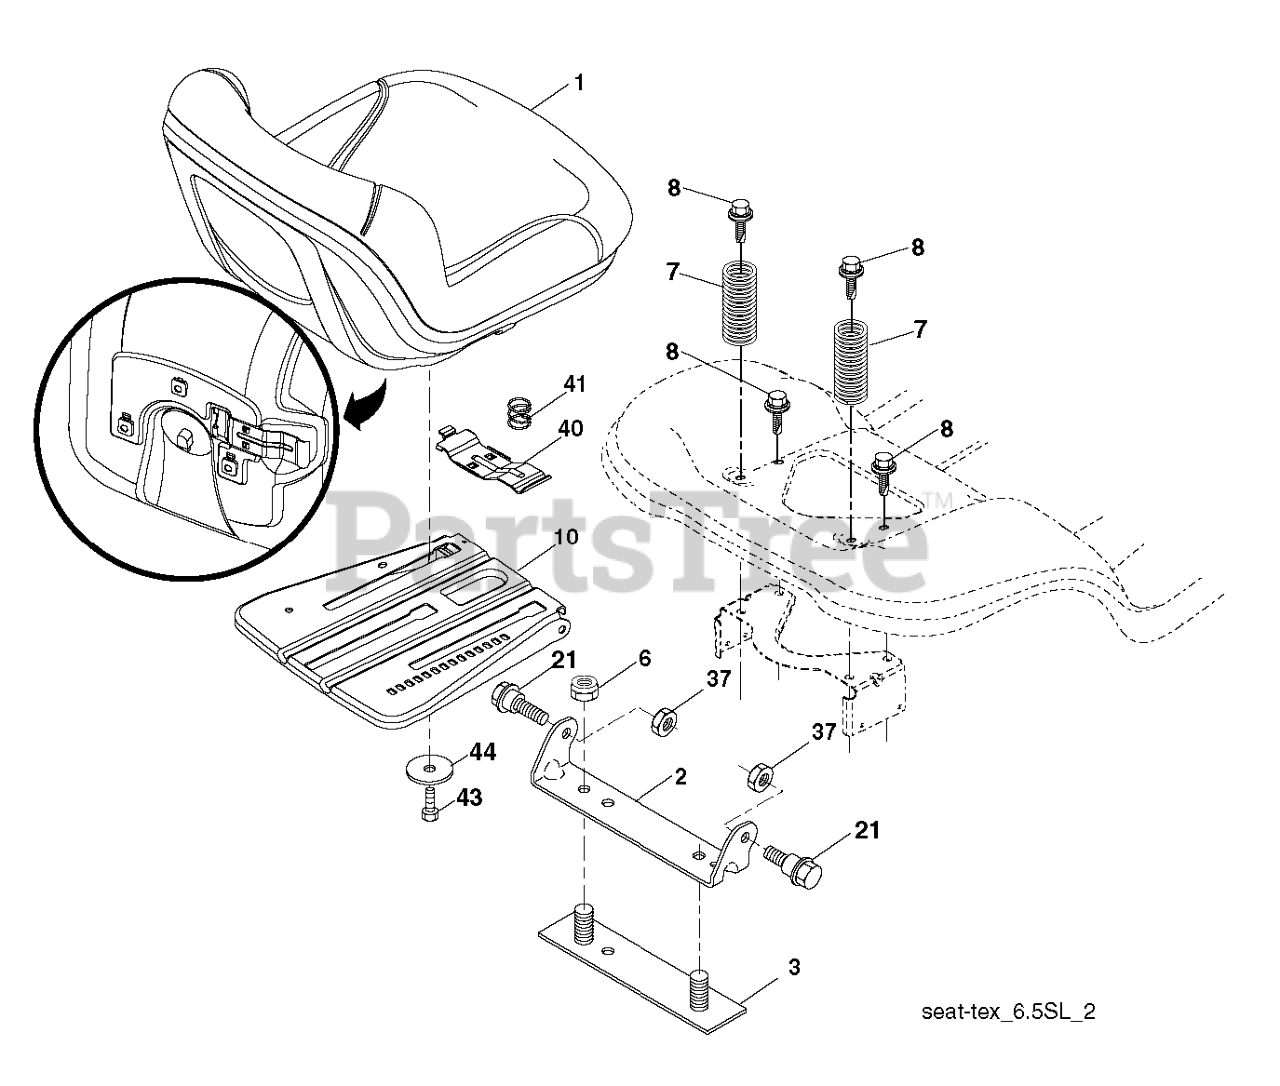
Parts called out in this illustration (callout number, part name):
1	SEAT.TH151.GREY.PREM.HUSQ.MI
2	BRKT.PIVOT.FENDER
3	STRAP
6	NUT
7	SPRING COMPRESSION
8	BOLT.5/16-18UNCX3/4 W/SEMS.BLK
10	PAN.ASM.SEAT.3PT
21	BOLT.SHOULDER.5/16-18
37	NUT.71038.31-18.HEX.NYLOCK
40	HANDLE.SLIDE.SEAT.TEX.GREY
41	SPRING.LATCH.SEAT.TEX
44	WASHER 13/32 X 2-3/8 X 12GA
